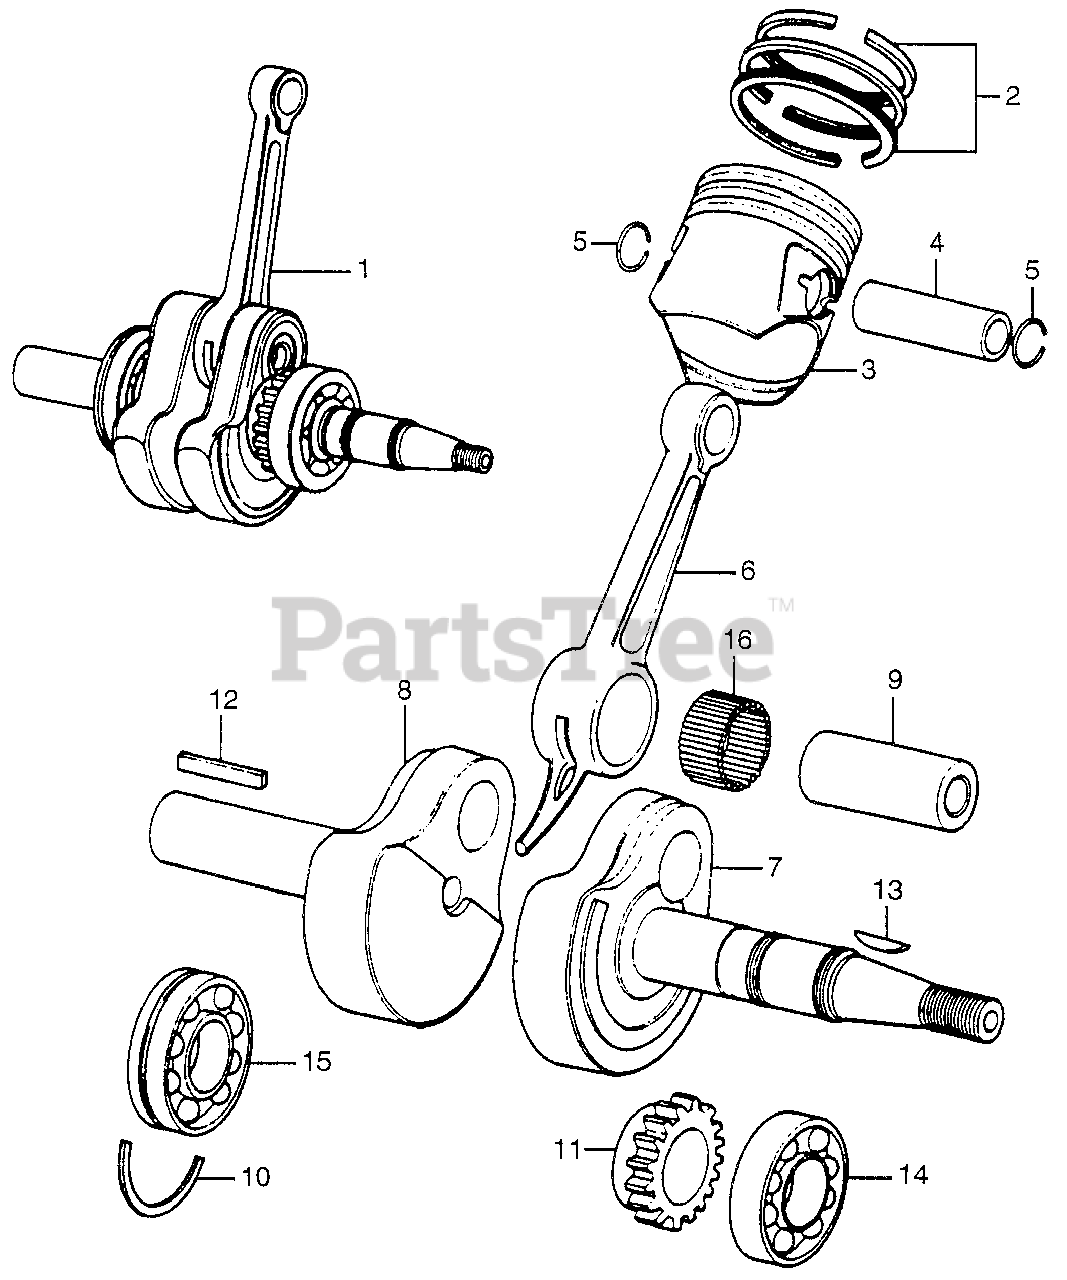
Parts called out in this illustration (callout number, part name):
1	CRANKSHAFT ASSY.
1	CRANKSHAFT
2	RING SET, PISTON (STD)
2	RING SET, PISTON (OS 0.25)
2	RING SET, PISTON (OS 0.50)
2	RING SET, PISTON (0.75)
3	PISTON (STD) (NOT AVAILABLE)
3	PISTON (OS 0.25)
3	PISTON (OS 0.50)
3	PISTON (0.75)
4	PIN, PISTON
5	CLIP, PISTON PIN (18MM)
6	ROD, CONNECTING
7	CRANKSHAFT, R.
8	CRANKSHAFT, L.
9	PIN, CRANKSHAFT
10	RING, BALL BEARING SET (NOT AVAILABLE)
11	GEAR, TIMING
12	KEY (7X7X33)
13	KEY, WOODRUFF (NOT AVAILABLE)
14	BEARING, BALL (6304S) (NOT AVAILABLE)
15	BEARING, RADIAL BALL (6206SHS) (NOT AVAILABLE)
16	ROLLER, ROD (2.48X18.8)
